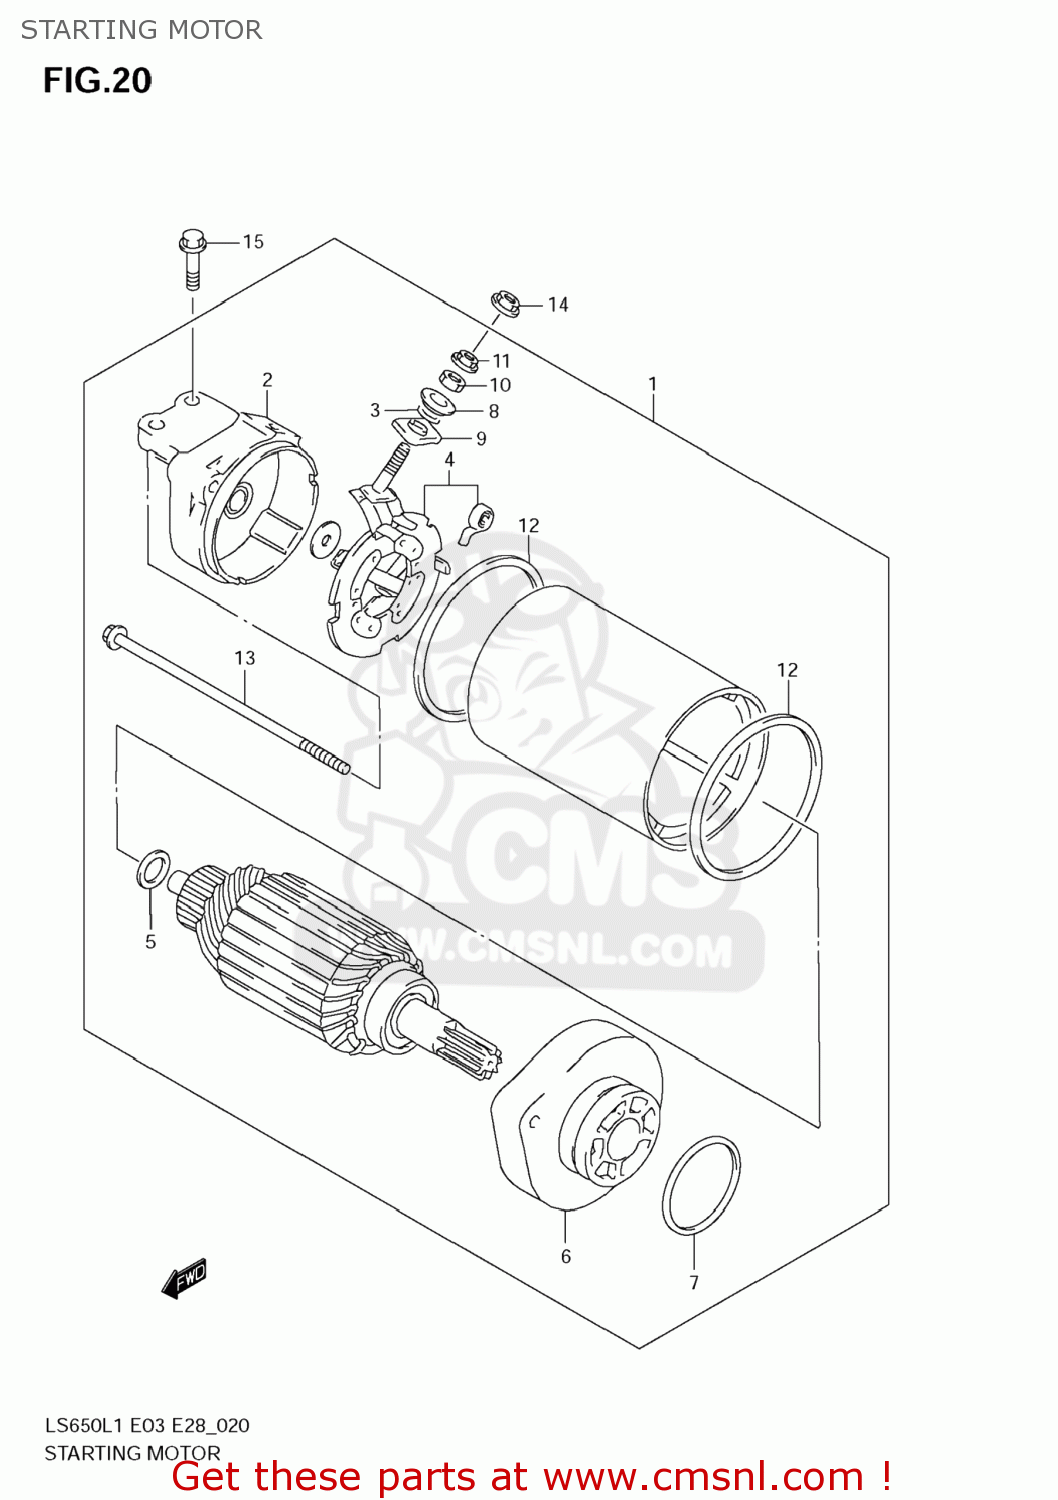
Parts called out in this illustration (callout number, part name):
1	MOTOR ASSY,STARTING
2	FRAME ASSY
3	O RING
4	HOLDER SET,BRUSH
5	SHIM SET,STARTING MOTOR
6	HOUSING ASSY
7	O RING
8	BUSHING
9	BUSHING
10	NUT
11	NUT
12	O RING
13	BOLT
14	NUT
15	BOLT(6X20)
